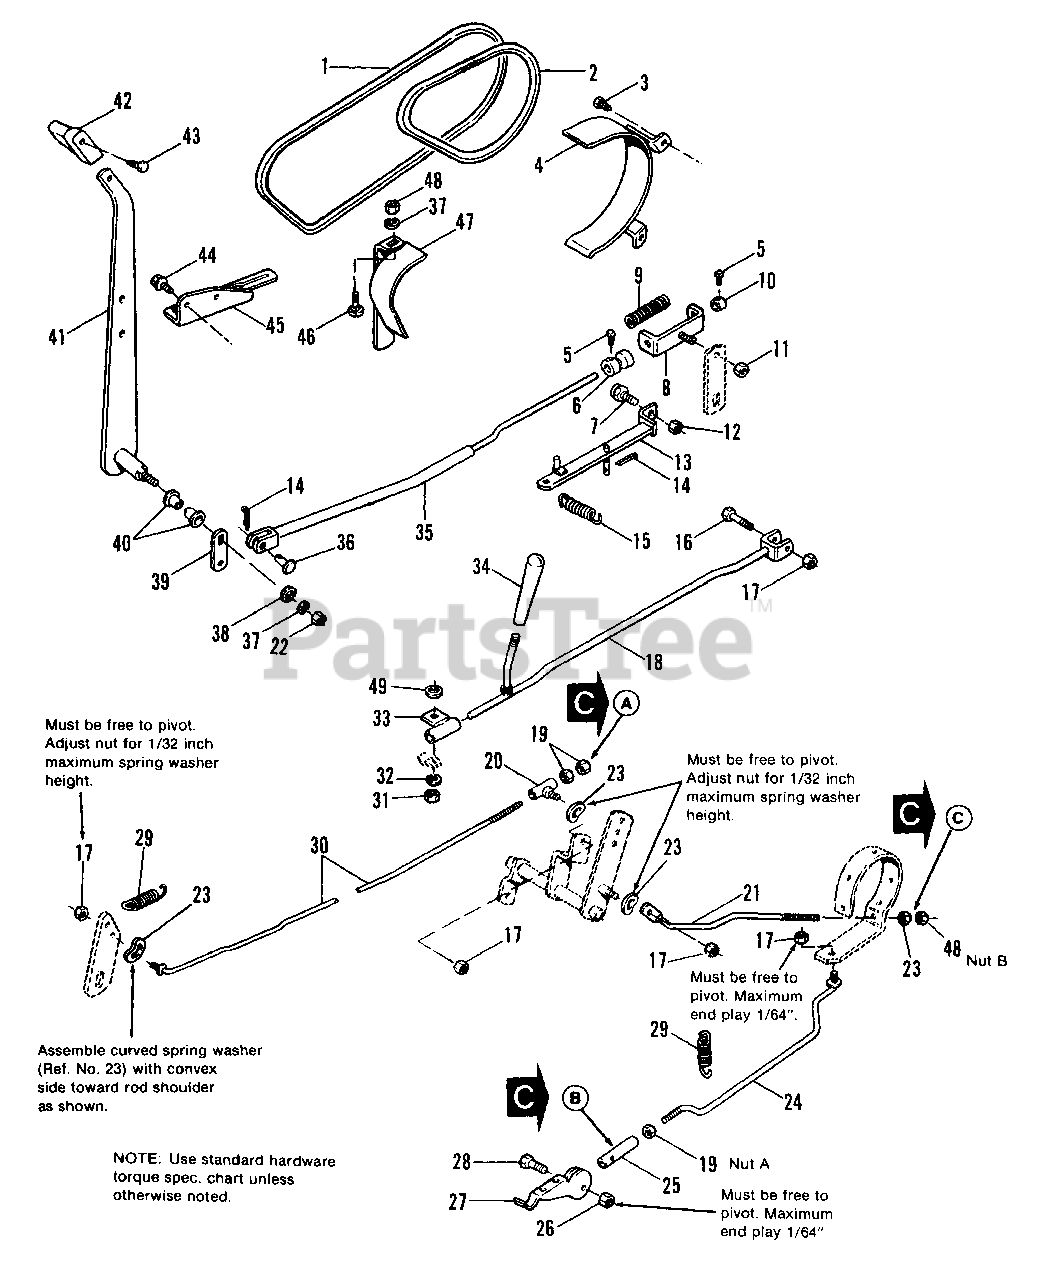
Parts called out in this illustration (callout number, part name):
1	V-BELT, Drive, Main
2	V-BELT, Drive, Secondary
3	SCREW, Hex, Taptite, 5/16-18 x 1/2
4	GUARD ASSY., Pulley
5	SETSCREW, 1/4-20 x 3/8
6	DETENT, Brake
7	PAD ASSY., Brake
8	GUIDE ASSY., Rod
10	COLLAR, Set
11	LOCKNUT, Hex, 3/8-16
12	LOCKNUT, Hex, Jam, 5/16-18
13	LEVER ASSY., Brake
14	PIN, Cotter, 3/32 x 3/4
16	CAPSCREW, Hex Hd., 5/16-18 x 1-1/2
17	LOCKNUT, Hex, 5/16-18
18	ROD ASSY., Shift
19	NUT, Hex, Full, 5/16-18
20	GUIDE ASSY., Rod
21	ROD, Brake
22	LOCKNUT, Hex, Esna, 3/8-16
23	WASHER, Curved Spring
24	ROD ASSY., Parking Brake
26	LOCKNUT, Hex, 1/4-20
27	LEVER, Parking Brake
28	CAPSCREW, Hex Hd., 1/4-20 x 1
30	ROD ASSY., Brake & Clutch
31	NUT, Hex, Full, 1/4-20
32	LOCKWASHER, 1/4
33	GUIDE ASSY., Shift Rod
34	HANDLE, Shift Rod
35	ROD ASSY.
37	LOCKWASHER, 3/8
38	WASHER, Plain, 3/8
41	LEVER ASSY.
43	SCREW, Thread Forming, 1/4-20 x 1-1/8
44	SCREW, Hex, Whizlock, Flange, 5/16-18 x 1/2
46	BOLT, Carriage, 3/8-16 x 3/4
47	GUARD ASSY., Belt
48	NUT, Hex, Full, 3/8-16
49	WASHER, Plain, 3/8
